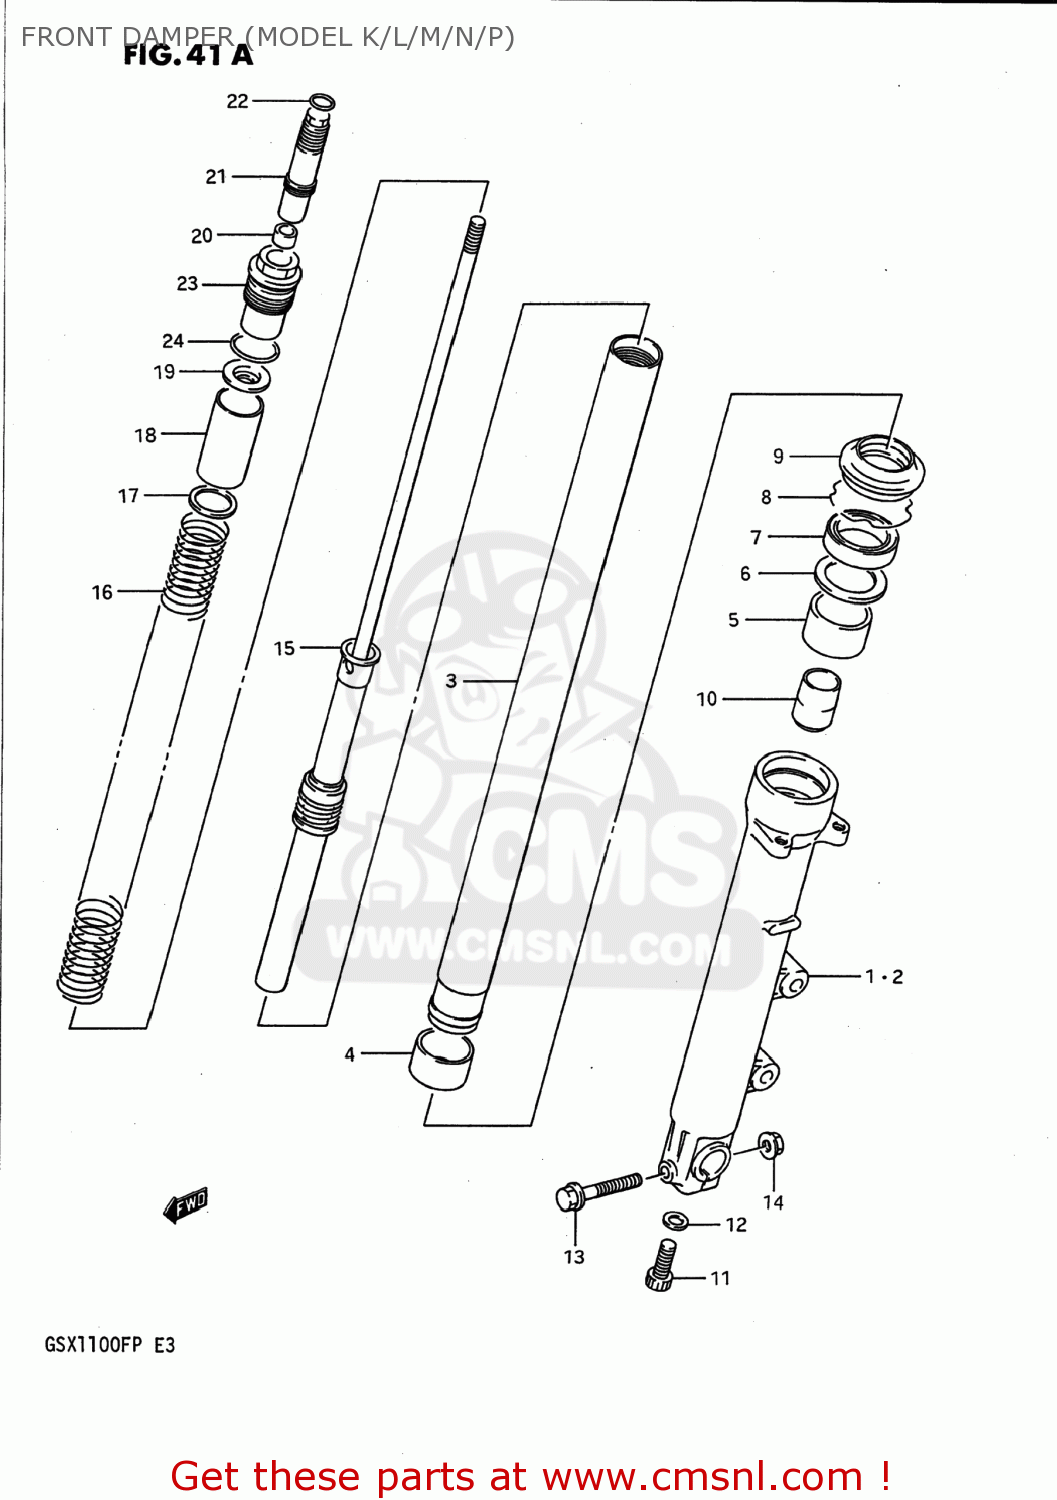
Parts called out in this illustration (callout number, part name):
1	TUBE,OUTER,RIGHT
2	TUBE,OUTER,LEFT
3	TUBE,INNER
4	BUSH,SLIDE
5	BUSH,GUIDE
6	SPACER,SEAL
7	SEAL,OIL
8	CIRCLIP,FORK OIL SEAL
9	BOOT
10	PIECE,OIL LOCK
11	BOLT(8X27)
12	GASKET (NAS)
13	BOLT 8X55
14	NUT
15	DAMPER
16	SPRING,FR FORK
17	JOINT,SPRING
18	COLLAR,SPRING(32.9X34X50)
19	SEAT,SPRING,UPPER
20	NUT,ROD
21	ADJUSTER,SPRING
22	O RING
23	BOLT,FORK
24	O RING
